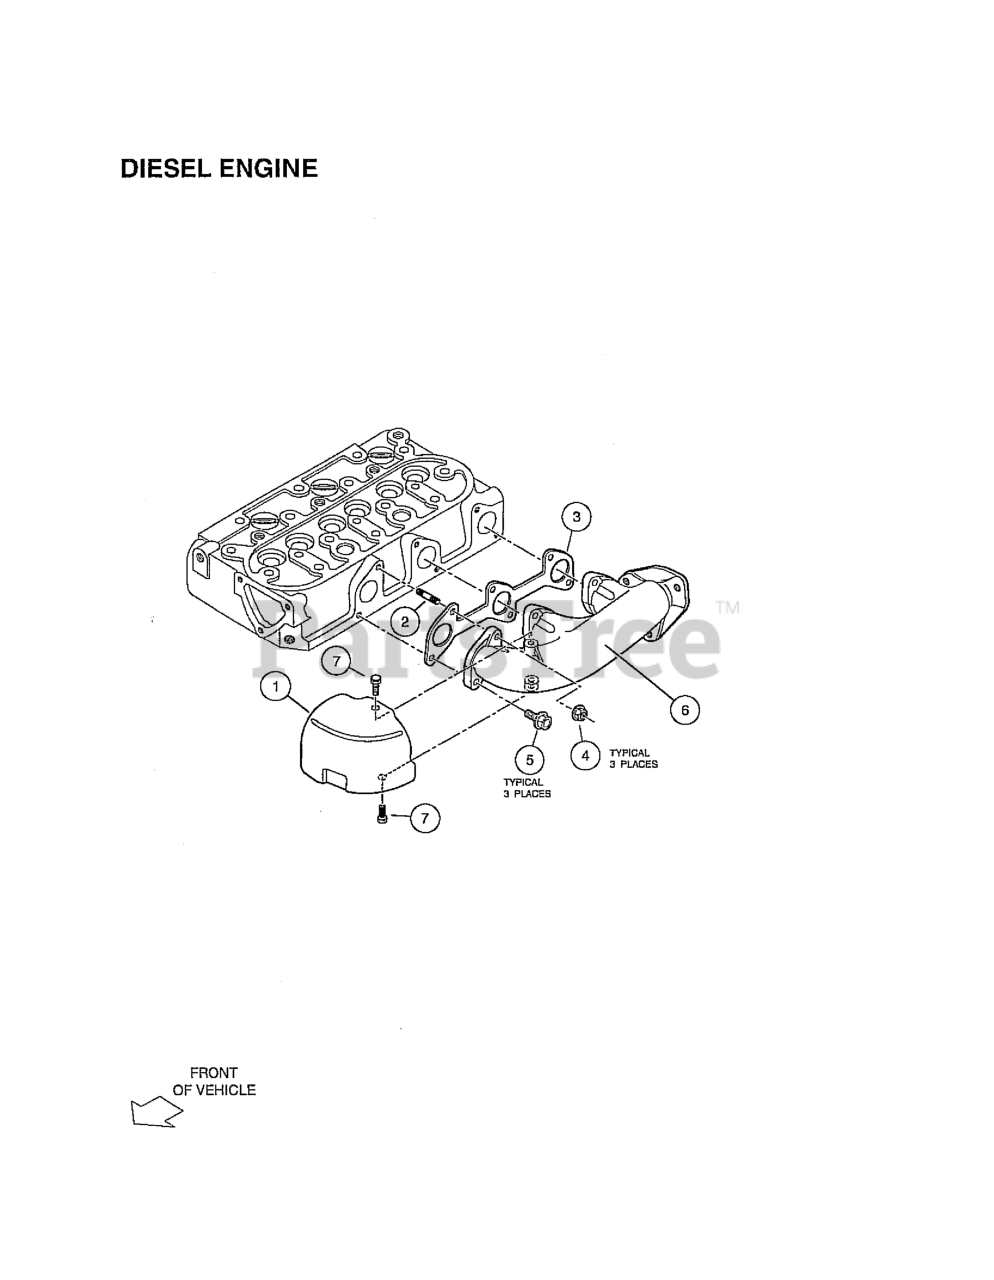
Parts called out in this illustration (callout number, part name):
1	Cover, Heat Proof
2	Stud, M6 X 26
3	GASKET, EX-MANIFOLD
4	Nut, Flange, M6, Ubs
5	Bolt, Flange Head, M6 X 1 X 16
6	MANIFOLD, EXHAUST, D722
7	BOLT, D722, EXHST MANFLD COVER
